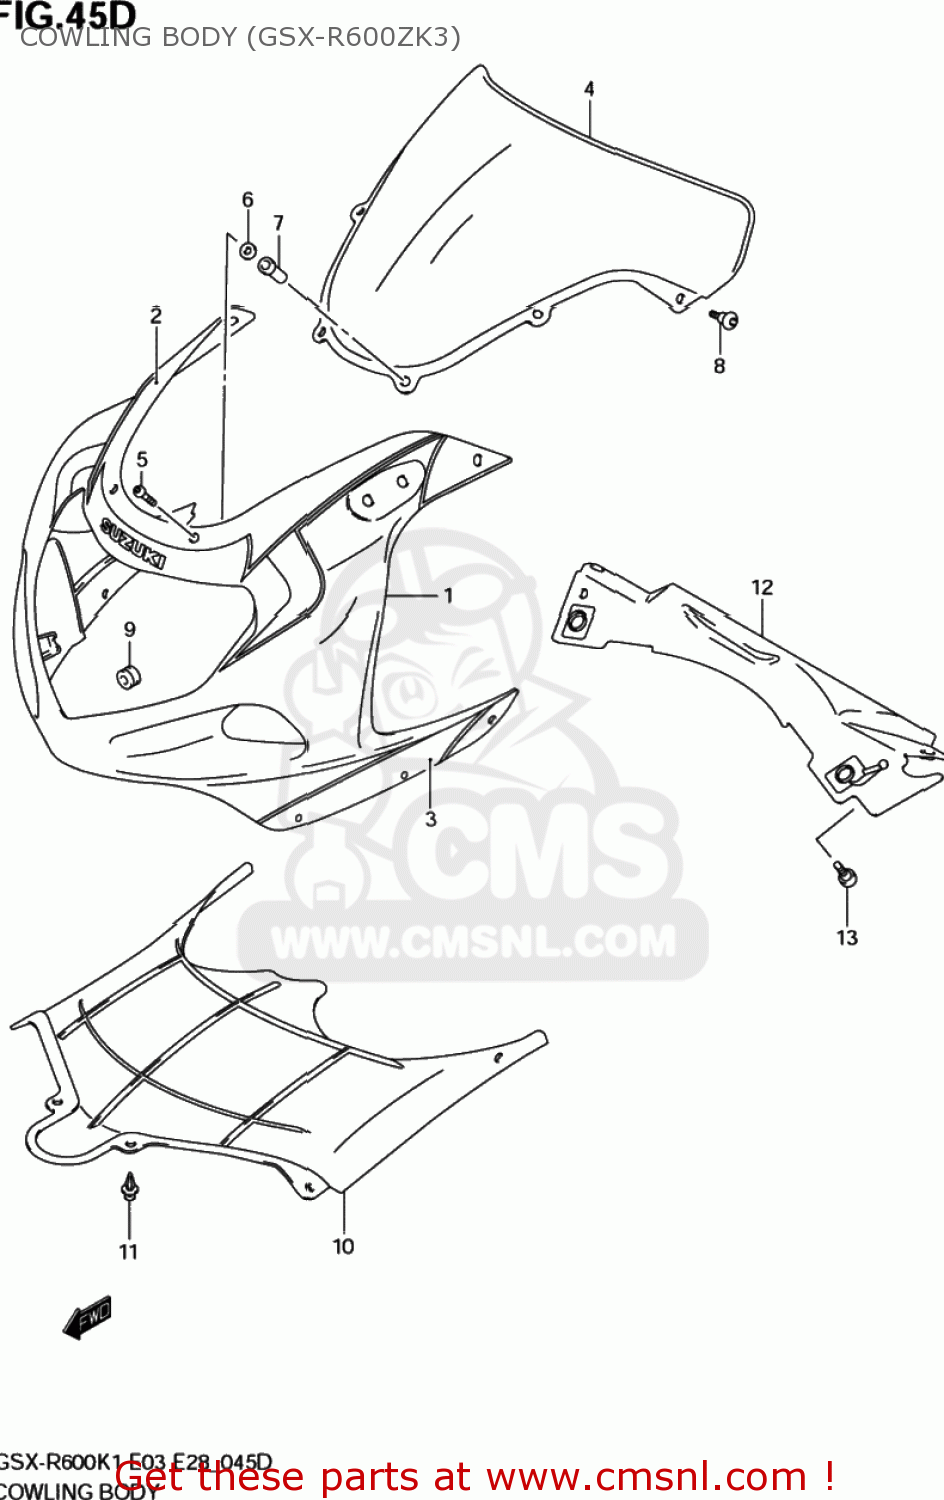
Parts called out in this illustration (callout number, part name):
1	COWLING,BODY(YELLOW)
2	TAPE SET,FR
3	TAPE SET,SIDE
4	WINDSCREEN
5	SCREW(5X14)
6	WASHER
7	NUT
8	SCREW(5X16)
9	CUSHION
10	COVER,BODY COWLING
11	CLIP(BLACK)
12	COVER,COWLING FR LWR
13	BOLT(5X16)
